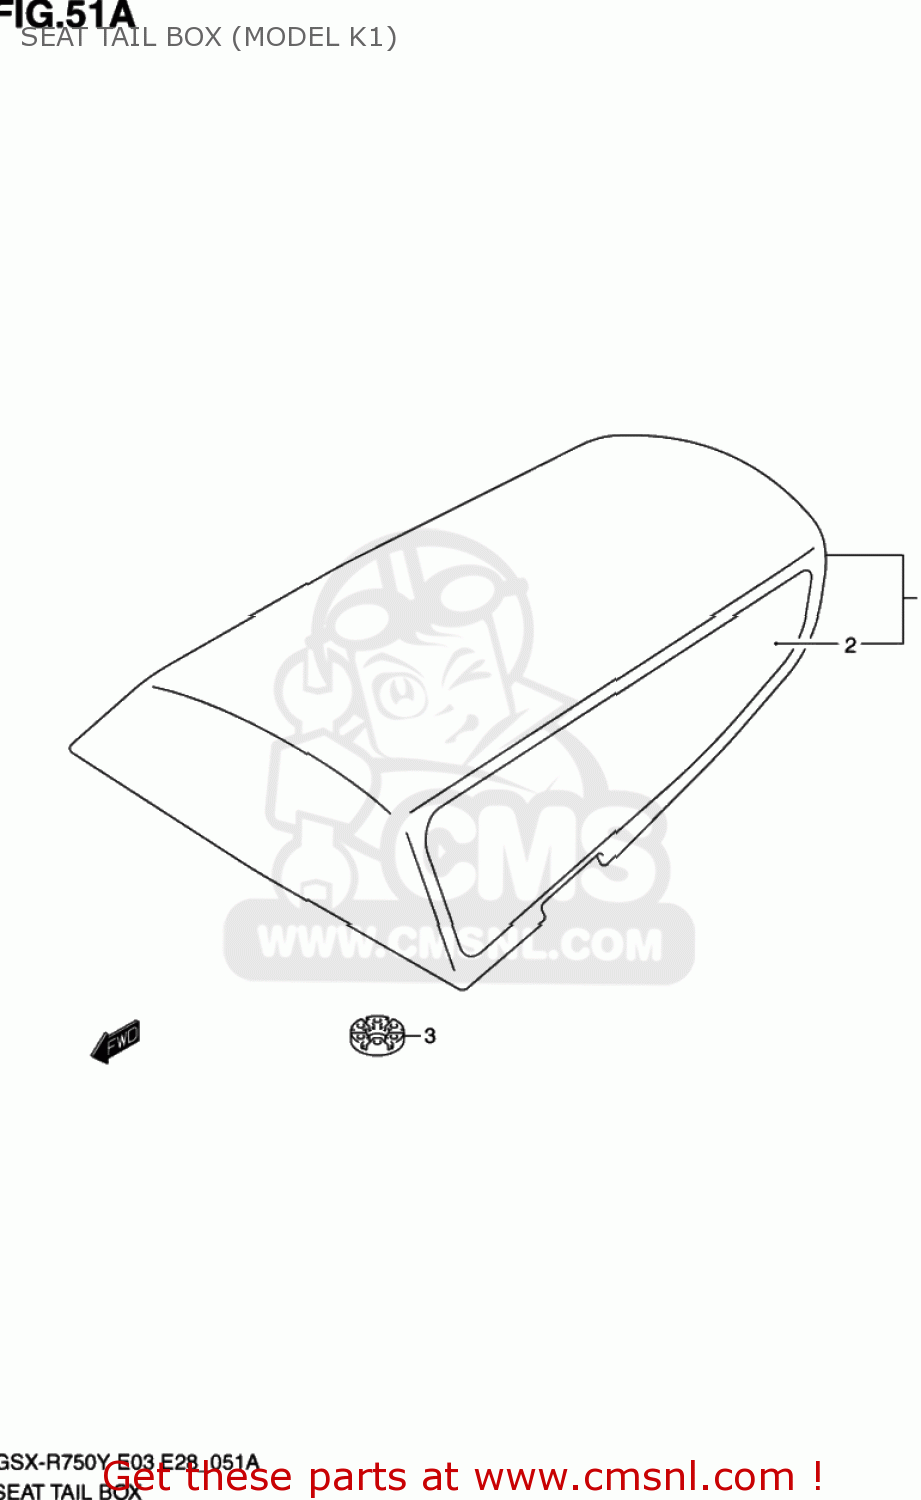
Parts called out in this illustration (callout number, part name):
1	BOX ASSY,SEAT
2	TAPE SET,BOX SEAT TAIL(BLACK)
3	CUSHION
